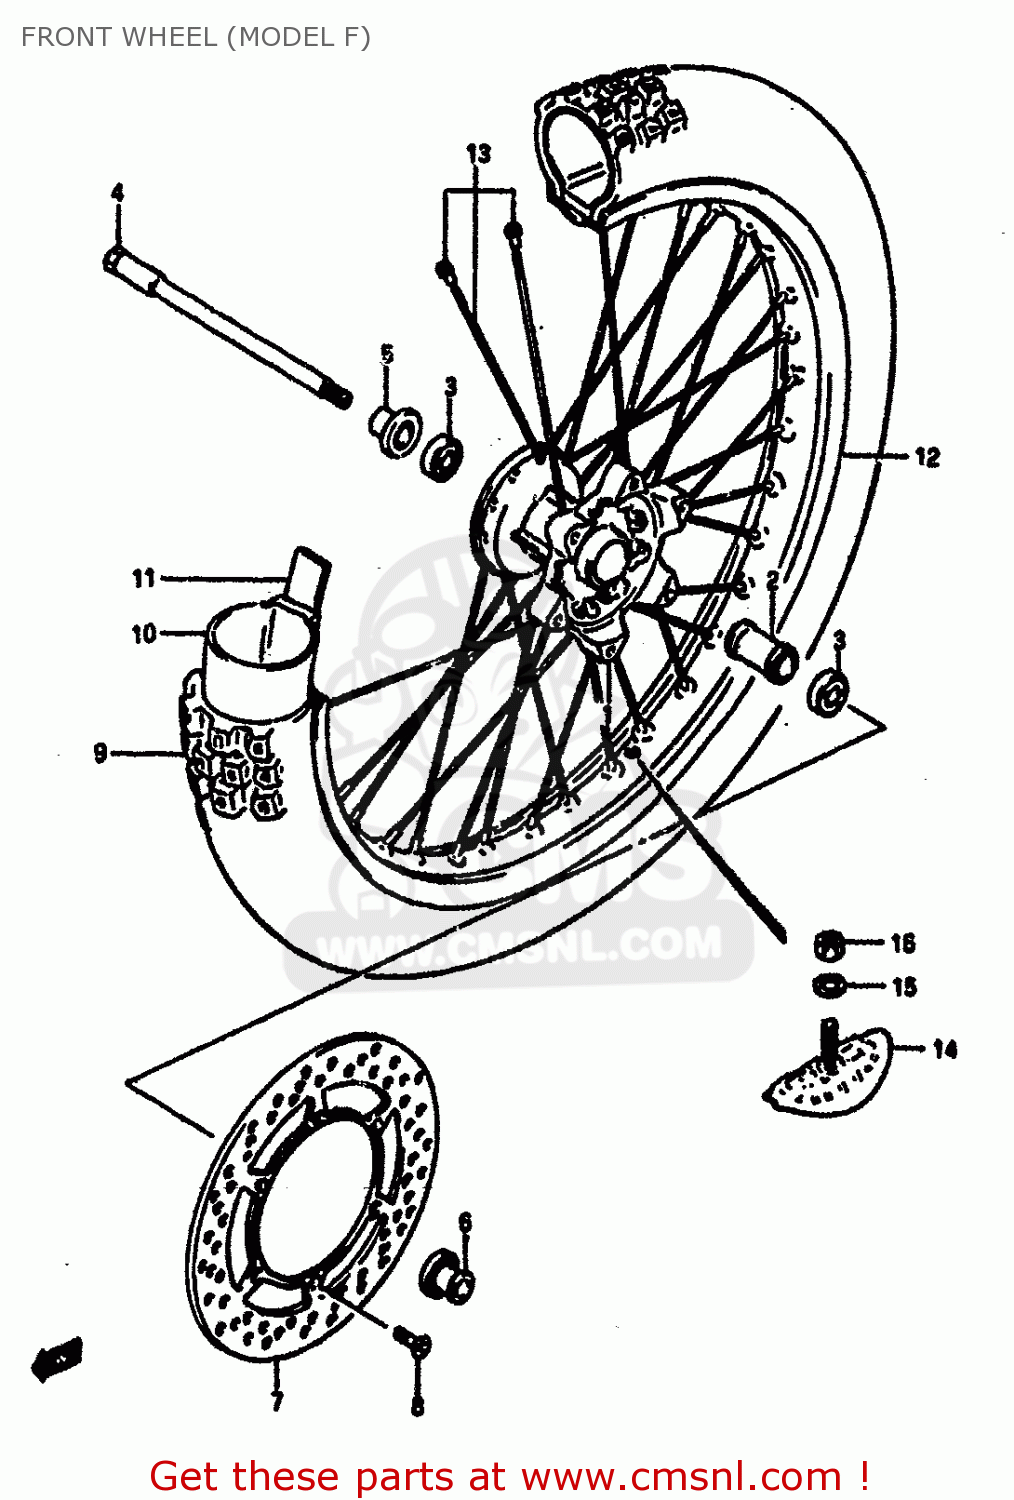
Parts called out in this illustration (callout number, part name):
1	HUB,FRONT
2	SPACER,FRONT HUB BEARING
3	BEARING
4	AXLE,FRONT
5	SPACER,FRONT AXLE,RIGHT
6	SPACER,FRONT AXLE,LEFT
7	DISC,BRAKE
8	SCREW
9	TIRE,FRONT
10	TUBE,INNER
11	PROTECTOR,WHEEL INNER
12	RIM,FRONT WHEEL (1.60X21)(
13	SPOKE SET,FRONT
14	STOPPER,BEAD
15	WASHER
16	NUT
